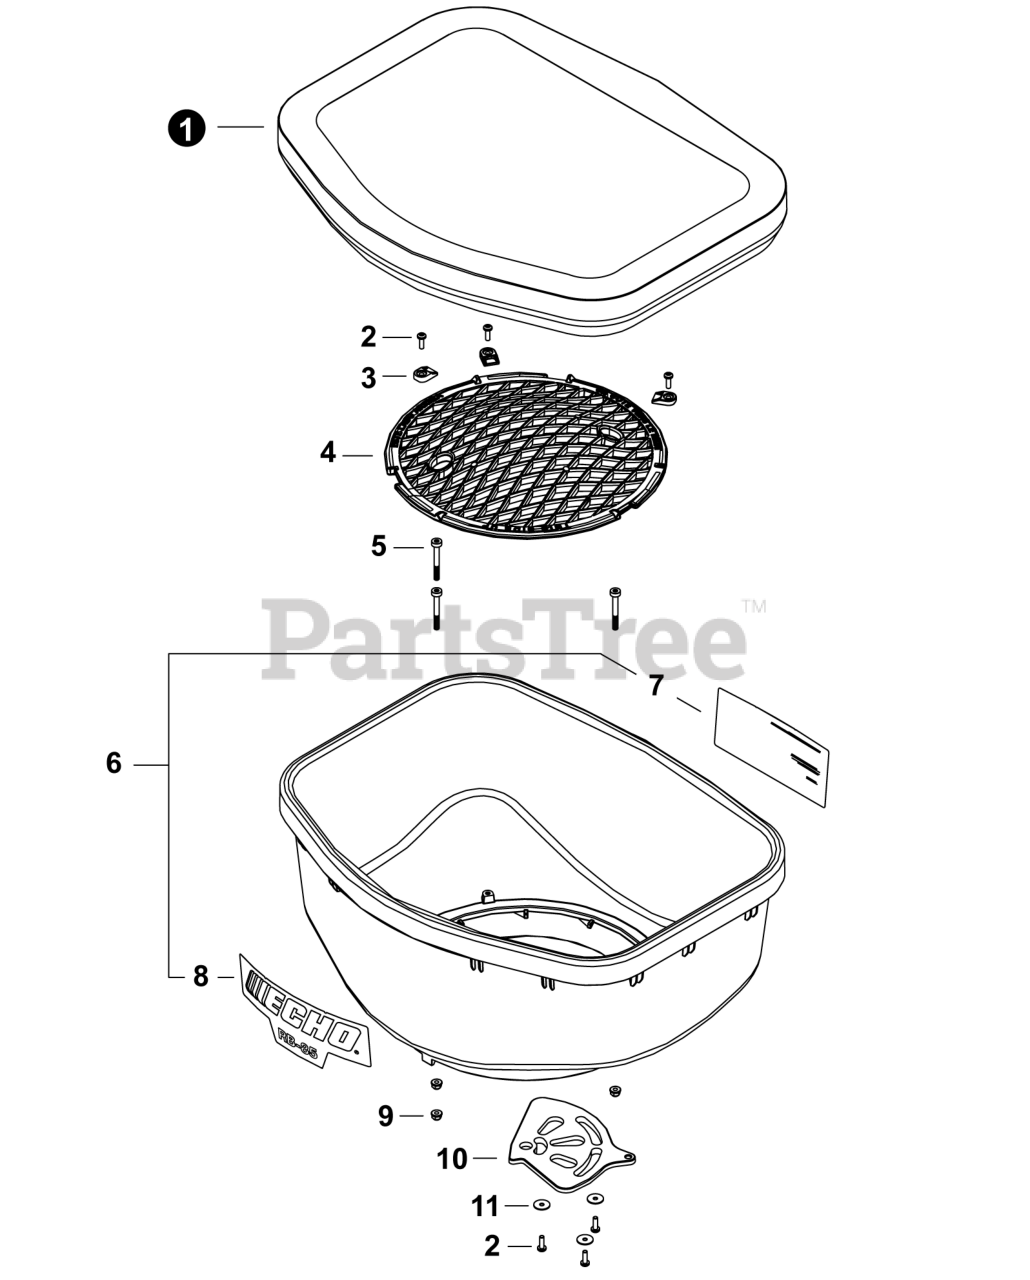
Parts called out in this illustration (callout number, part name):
1	COVER, HOPPER
2	BOLT, TORX 5x16
3	CLIPS, SCREEN
4	SCREEN, HOPPER
5	BOLT, M6 X 50MM
6	HOPPER ASSY
7	LABEL - OPERATION
8	LABEL - RB-85
9	NUT, FLANGE M6
10	PLATE, REGULATOR
11	WASHER 5
